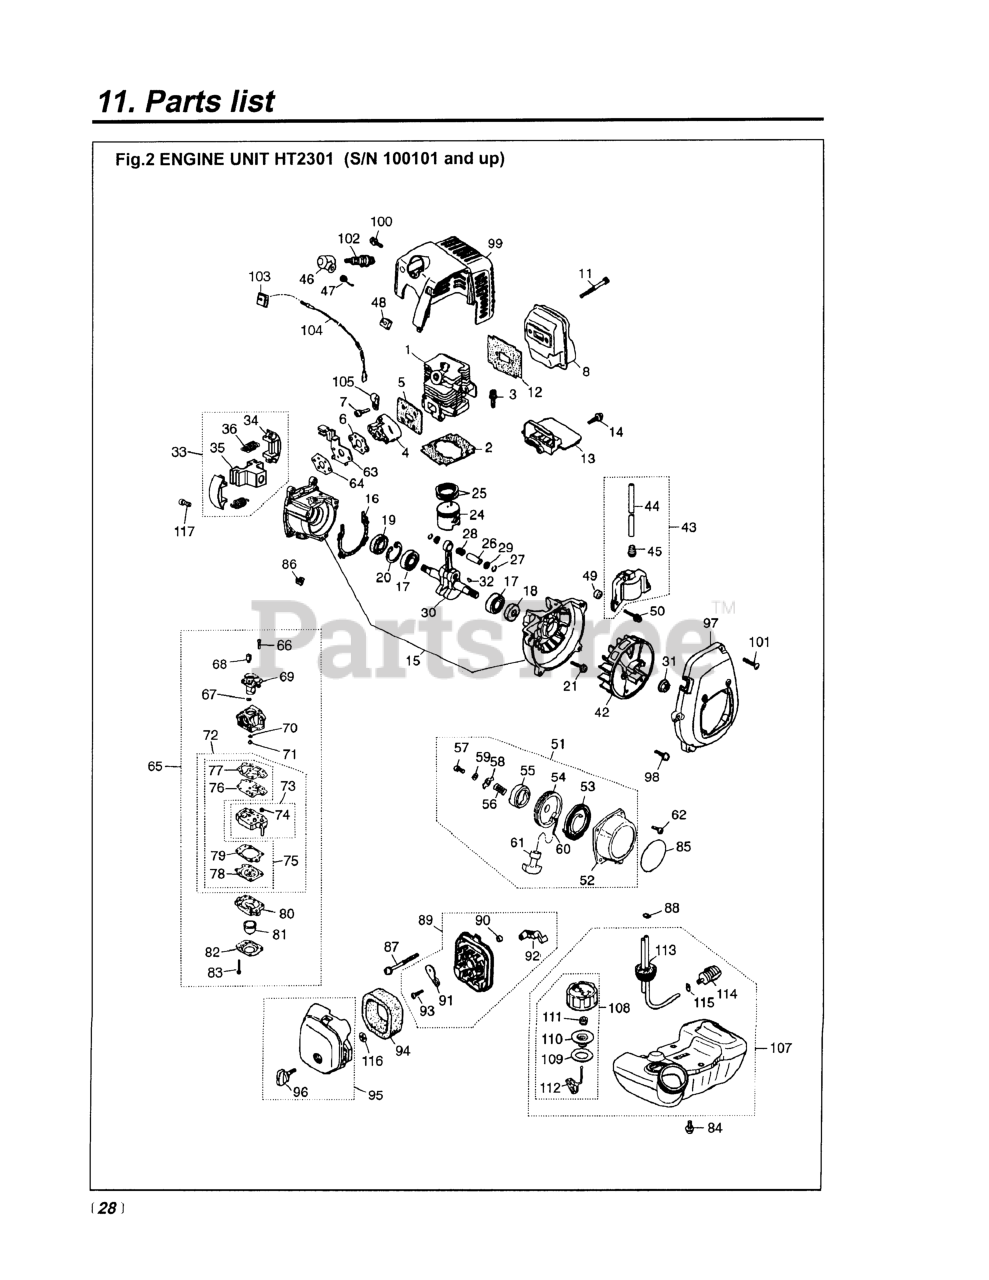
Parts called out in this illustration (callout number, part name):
1	CYLINDER
2	GASKET, BASE (RPLS -12212)
3	BOLT, M5 X 22
4	INSULATOR (REPLACES -13162)
5	GASKET (RPLS -13120)
6	GASKET (REPLACES -13130)
7	SCREW, M5X20 (RPLS.1400-75510)
11	BOLT, M5 x 50
12	GASKET, MUFFLER (RPLS -15111)
14	SCREW, M4 X 16
15	CRANKCASE-C
16	GASKET (RPLS -21140)
17	BEARING
18	SEAL, OIL (RPLS 1100-21210)
19	SEAL, OIL (RPLS 1140-21220)
20	RING, SNAP, M28 x 1.2
21	BOLT, M5 X 30
24	PISTON (REPLACES 1140-41110)
25	RING, PISTON (RPLS 1850-41210)
26	PIN, PISTON 5x8x26
27	RING, SNAP (RPLS 1101-41320)
28	BEARING (RPLS 1140-41330)
29	WASHER
30	CRANKSHAFT (RPLS 1850-42000)
32	KEY
36	SPRING
43	COIL
45	CAP
46	CAP
47	SPRING
48	GROMMET
49	SPACER (RPLS -71260)
50	BOLT
52	CASE, RECOIL
53	SPRING
54	REEL (USE-75131)
55	5990-75141 (RPLS. 1861-75141)
56	SPRING (REPLACES -75150)
58	RETAINER
59	WASHER
60	ROPE
61	KNOB (REPLACES-75180)
62	SCREW, M4 x 12
63	BRACKET
64	GASKET (REPLACES -13130)
65	CARBURETOR
67	RING
68	SWIVEL
69	VALVE ASSY
70	RING, O
73	BODY, PUMP
74	SCREEN
76	DIAPHRAGM, PUMP
77	GASKET, PUMP
78	DIAPHRAGM
79	GASKET, DIAPHRAGM
80	BODY, PURGE
81	PUMP, PRIMING
82	COVER, PUMP
83	SCREW
85	LABEL (HT2301)
86	CAP, CABLE END
87	SCREW, M5 x 60
88	CLIP
89	BODY ASSY.
90	SLEEVE
91	PLATE, CHOKE
92	LEVER
93	SCREW (REPLACES 50030272)
94	ELEMENT
95	COVER ASSY (RPLS -82202)
96	KNOB (RPLS -82220)
97	COVER, FAN
98	SCREW, M5X20 (RPLS.1400-75510)
100	SCREW, M5 x 12
101	SCREW, HOUSING
105	CLAMP
107	TANK-A
108	CAP ASSY (RPLS -85201)
109	PACKING
110	HOLDER (REPLACES -85230)
111	FILTER
112	STOPPER
113	PIPE COMPLETE
114	FILTER (RPLS 1850-85300)
115	CLIP (REPLACES 2841-31280)
116	CLIP
